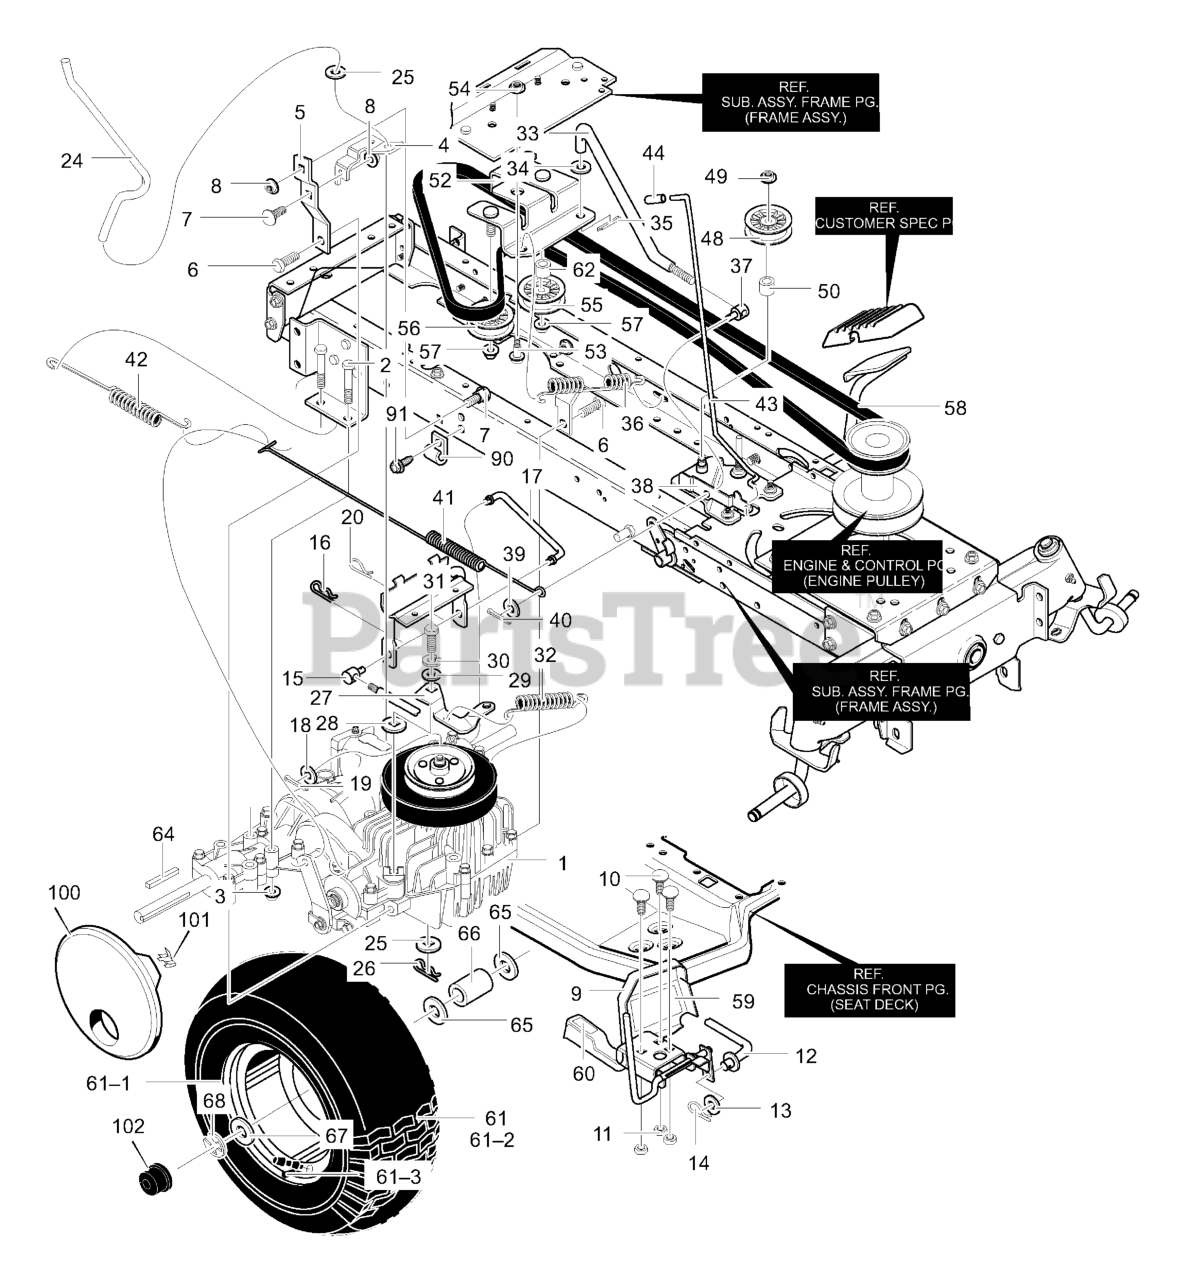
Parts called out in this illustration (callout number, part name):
1	Transaxle, Peerless **
3	NUT, 5/16-18
4	BRACKET, DISCONNECT
5	STRAP, RIGHT TORQUE
6	SCREW, 5/16-18 x 0.75
7	BOLT, CARRIAGE
8	NUT, 5/16-18 HEX
9	PEDAL ASSEMBLY, HYDRO
10	BOLT, 5/16-18X .75
11	NUT, 5/16-18 HEX
12	ROD, PEDAL LINK
13	WASHER
14	PIN, HAIR
15	ADJUST NUT
16	PIN, HAIR
17	ROD, HYDRO LINK
18	WASHER, FLAT
19	PIN, COTTER
20	PIN, HAIR
24	ROD, DISCONNECT
26	PIN, COTTER
27	ARM, DISCONNECT
29	WASHER
30	WASHER
31	SCREW, 1/4-28 X.75 NYLON
32	SPRING, EXTENSION
33	ROD, CLUTCH
35	PIN, COTTER
36	SPRING, CLUTCH
37	NUT, ADJUSTING
38	LATCH, PARK BRAKE
39	WASHER, FLAT
40	PIN, COTTER
41	SPRING, EXTENSION
42	SPRING, TENSION
43	ROD, PARKING BRAKE
48	PULLEY, IDLER
49	NUT, 3/8-16
50	SPACER 1/2 TO 17MM
52	BRACKET, IDLER
54	NUT, 3/8-16
55	PULLEY, IDLER
56	PULLEY, IDLER
57	NUT, 3/8-16
58	BELT, MOTION DRIVE
59	PAD, CONTROL PEDAL
60	PAD, TOE
61	TIRE & RIM 20X8.00-8
61-3	VALVE STEM
62	SPACER 1/2 TO 17MM
64	KEY, SQUARE
67	WASHER
70	SPACER 1/2 TO 17MM
90	RETAINER, WIRE
100	CAP, HUB
101	RETAINER
102	COVER, DUST
